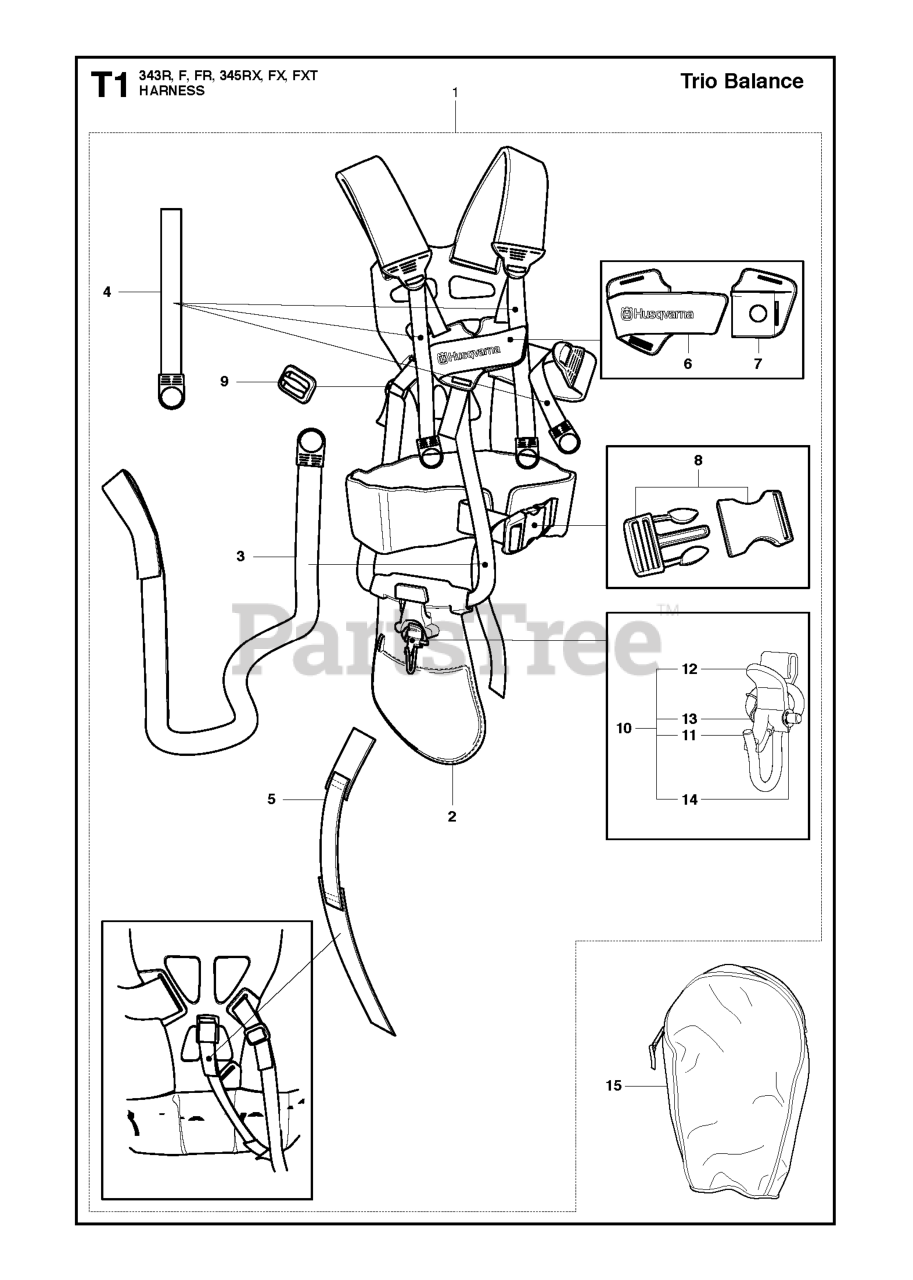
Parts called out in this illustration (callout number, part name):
1	HUS BALANCE X TRIO HARNESS
1	RP HARNESS TRIO BALANCE
6	FRONT PIECE
7	FRONT PIECE
9	RP CLIP
11	HOOK
12	CATCH *
13	SPRING
15	TOOL BAG
